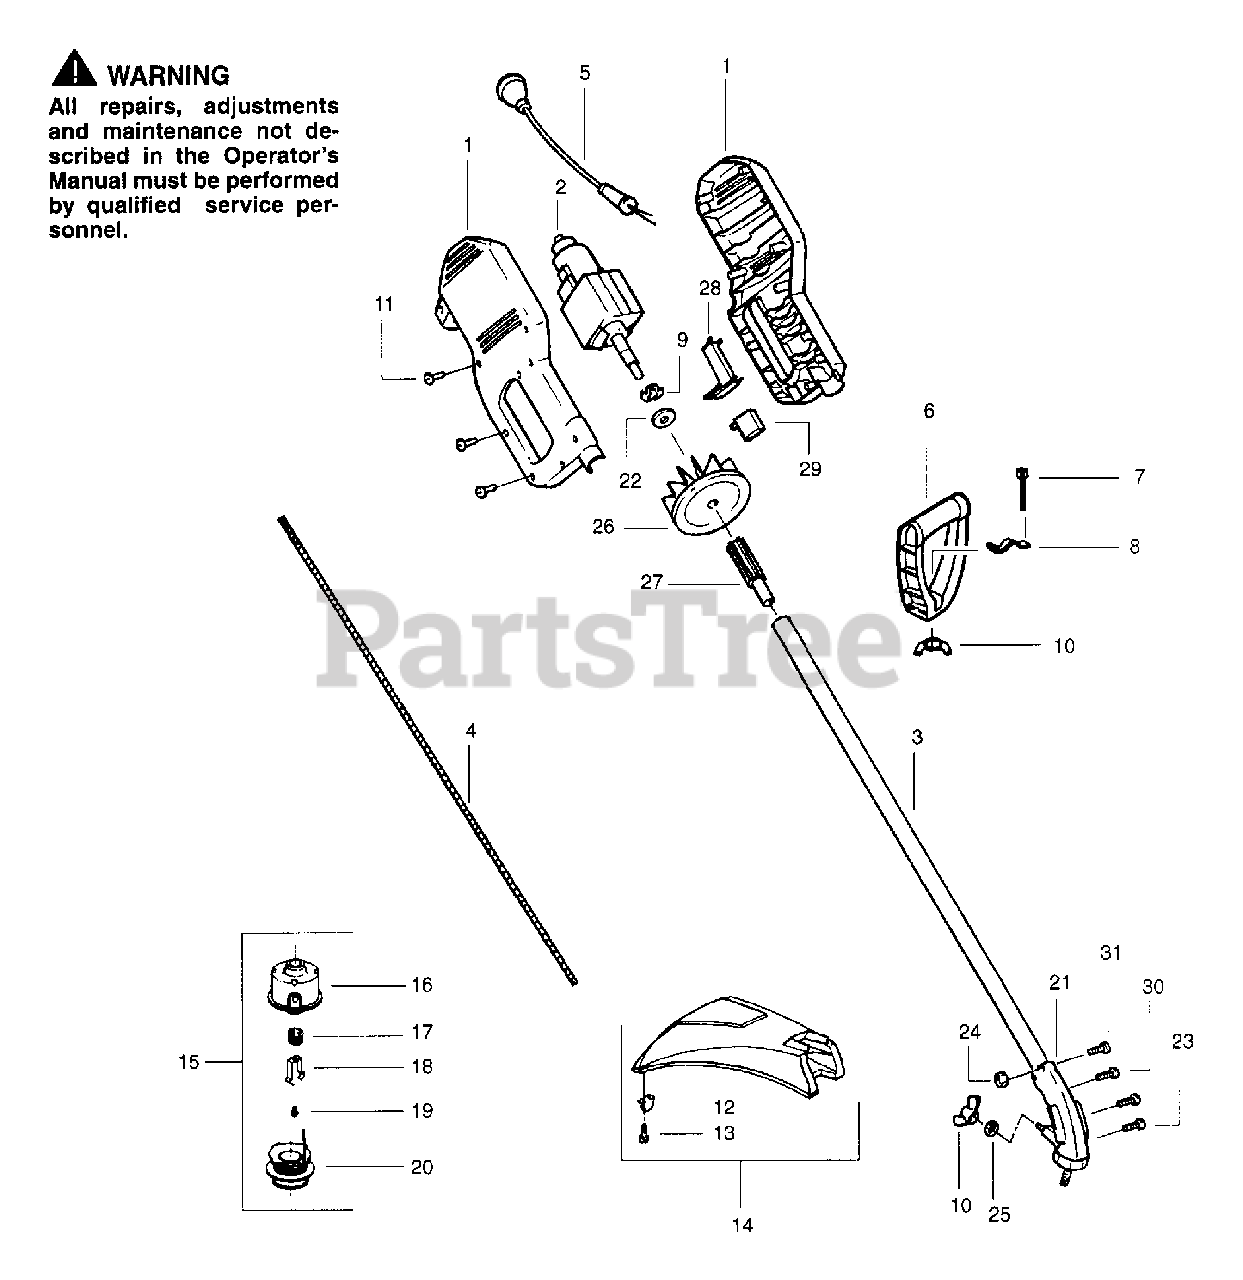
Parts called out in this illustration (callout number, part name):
1	Housing Set
3	Tube Ass'y.
4	Flex Shaft
5	Wiring Harness Ass'y.
6	Assist Handle
8	Clamp - Assist Handle
9	Clip Retainer
10	Wingnut
12	Line Limiter
13	Screw - Line Limiter
14	Shield Kit Ass'y.
15	Cutting Head Ass'y.
16	Hub Ass'y.
18	Retainer - Clip
19	Screw w/ Washer - Head
20	Spool w/Line
21	Gear Box Ass'y.
22	Washer - Drive Adaptor
27	Drive Adaptor Ass'y.
28	Trigger Switch
31	Screw
